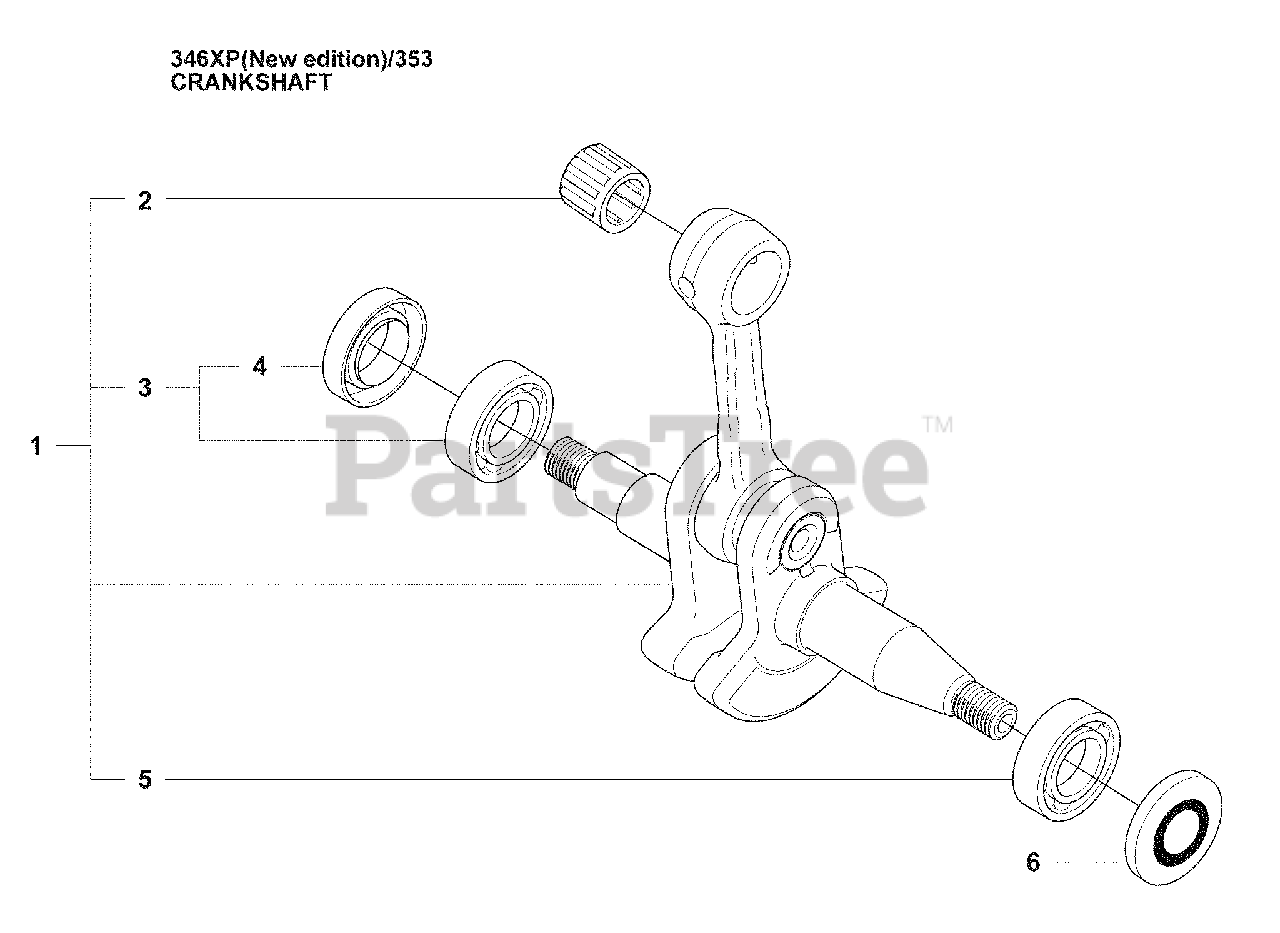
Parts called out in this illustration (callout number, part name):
1	Crankshaft
2	Support Bushing
3	Ball Bearing
4	Radial Seal
5	Ball Bearing, 6202C3 SK
